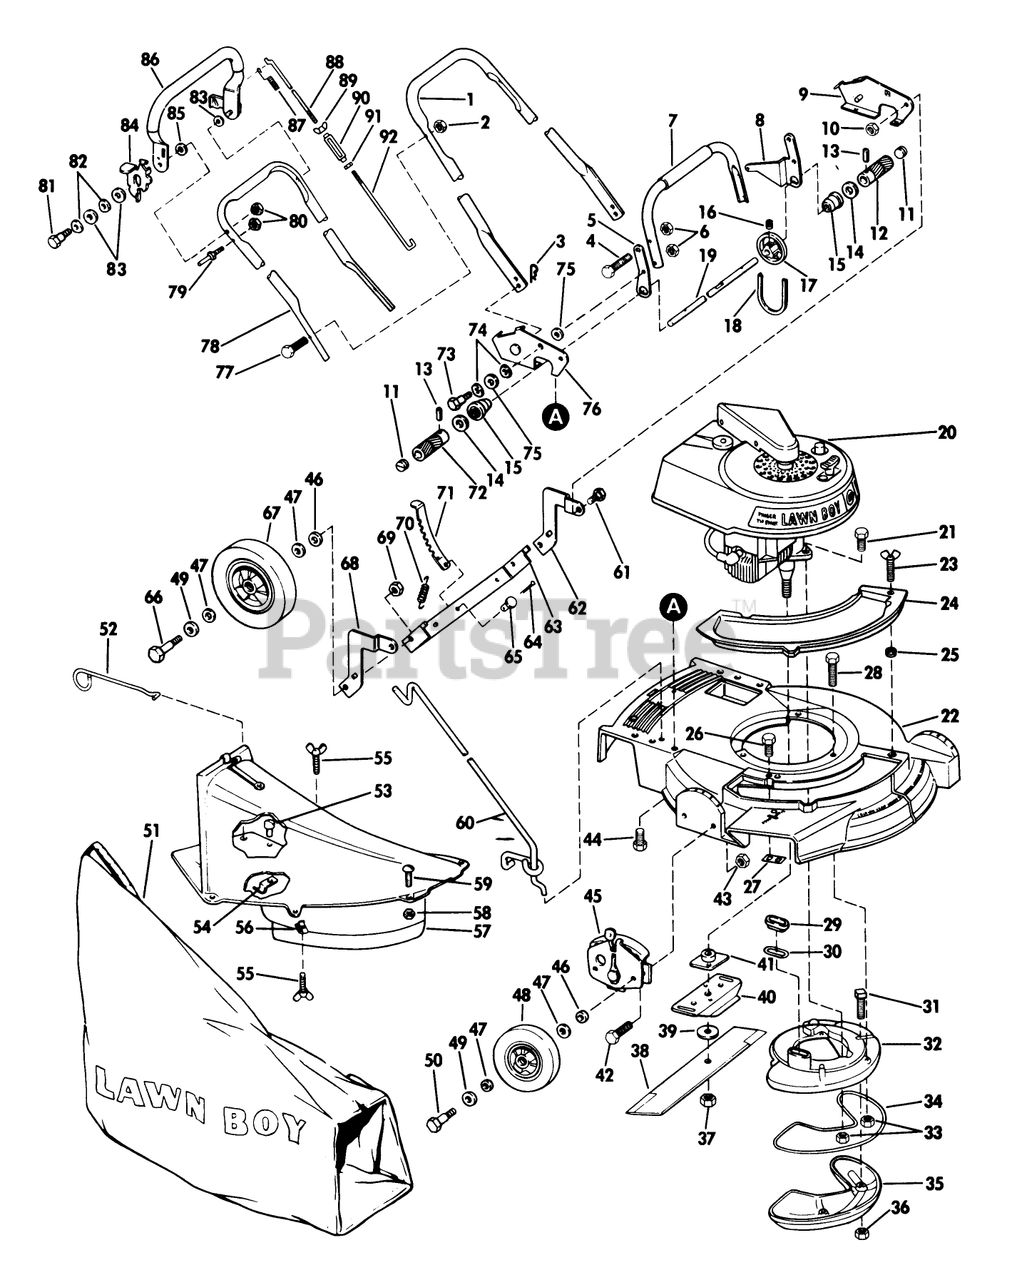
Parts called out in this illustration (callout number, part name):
3	HAIR PIN
11	GREASE PLUG
12	LEFT ROLLER
30	GASKET S
36	LOCKNUT E
37	NUT-BLADE
41	PLATE AND COLLAR ASM
46	WASHER WROUGHT
50	BOLT WHEEL
51	89802 LB WHOLE GOODS
56	SPEED NUT ARDEN
57	Chute Skirt Assembly (Includes Hardware)
61	BOLT-SHOULDER
69	LOCKNUT
70	SPRING N.A.S
73	BOLT PIONEER
75	WASHER M
81	BOLT PIONEER
83	WASHER M
